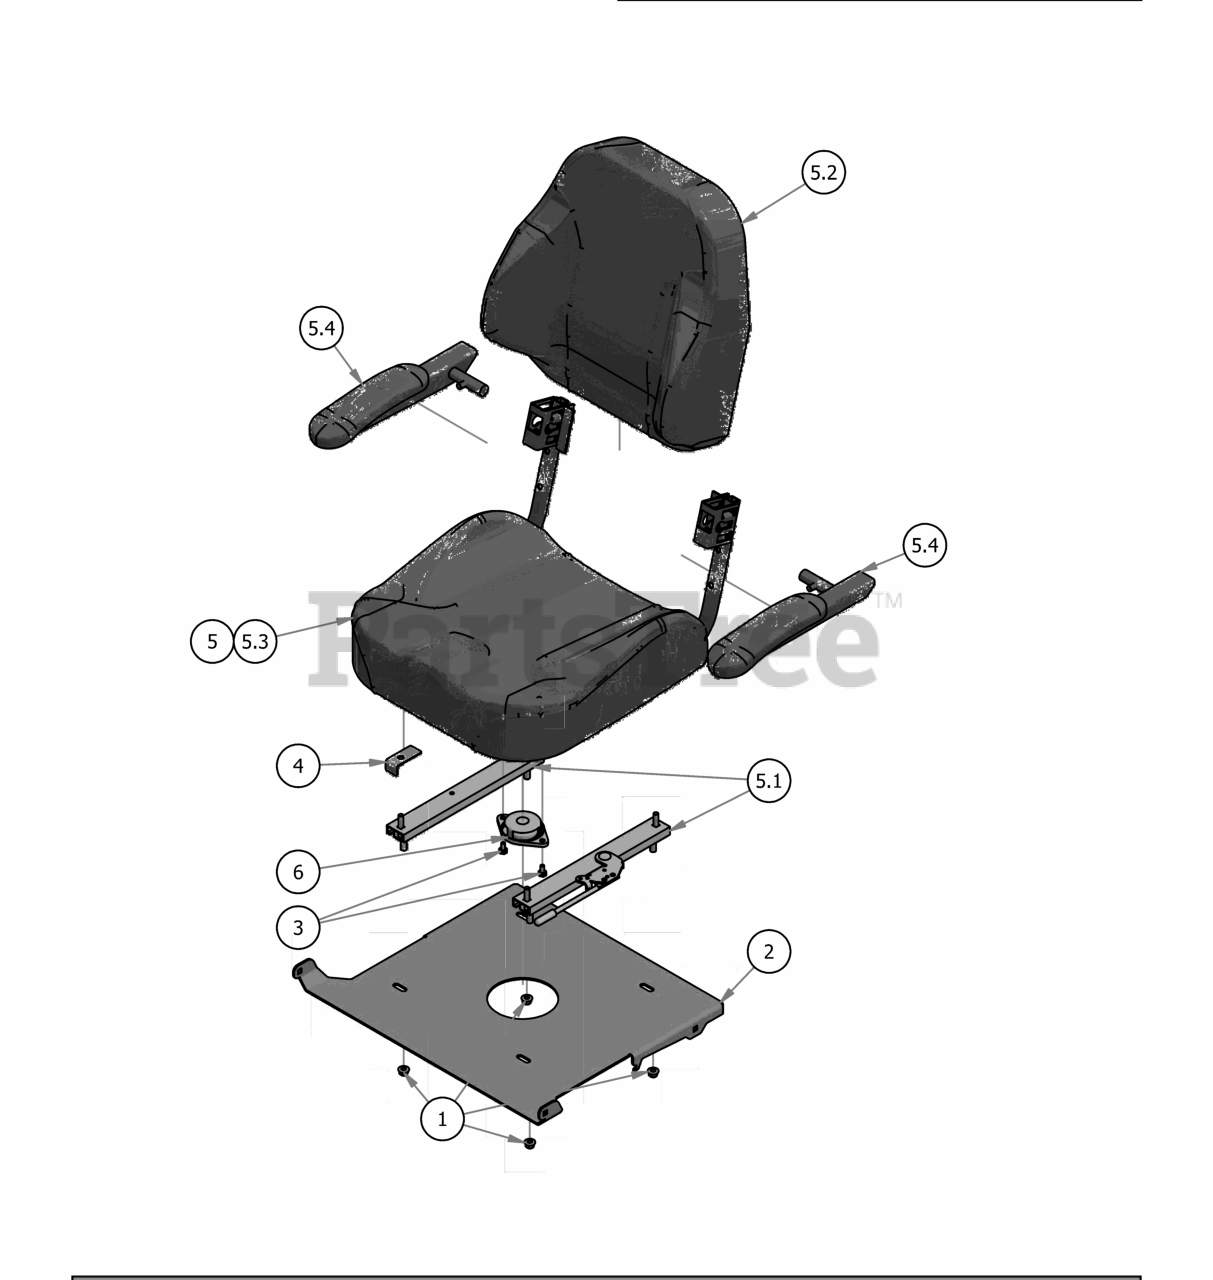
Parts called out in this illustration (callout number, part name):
1	5/16" Nylon Flange Nut
2	Seat Plate 2016
3	1/4-20x1/2 HWH Bolt Slot
4	MZ Seat Stop Bracket
5	2017 ZT Seat
5.1	Seat Rail Pair
5.2	Seat Back Cushion
5.3	Seat Bottom Cushion
5.4	Arm Rest (Pair)
6	Seat Safety Switch
